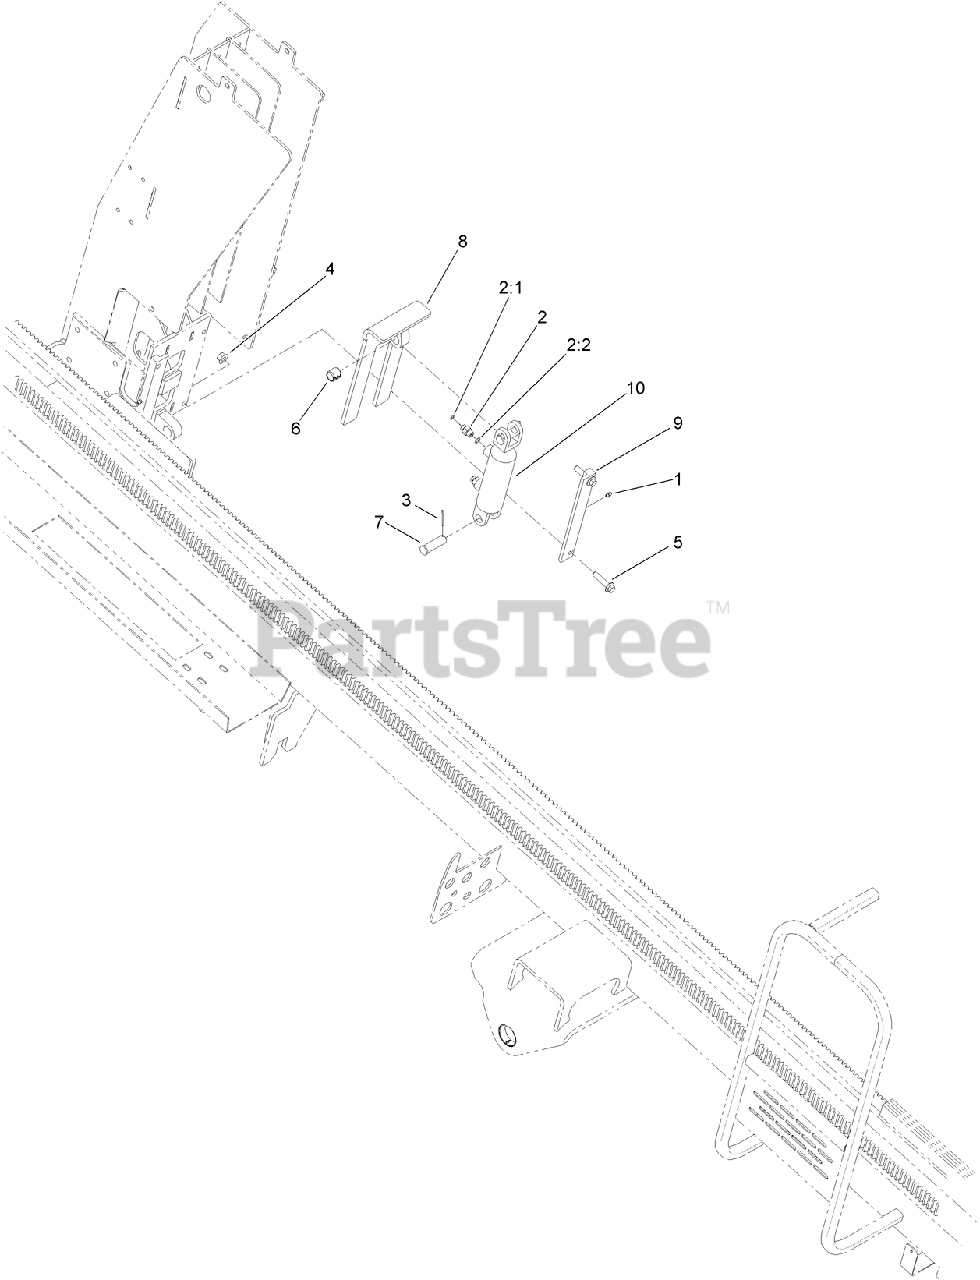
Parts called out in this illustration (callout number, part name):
1	FITTING-GREASE
2	FITTING-STRAIGHT
2:1	O-RING
2:2	O-RING
3	PIN-COTTER
4	NUT-HF
5	SCREW-HHF
6	BUSHING-SPRING
7	PIN-CLEVIS
9	GUIDE-ELEVATOR
10	HYD CYLINDER ASM
